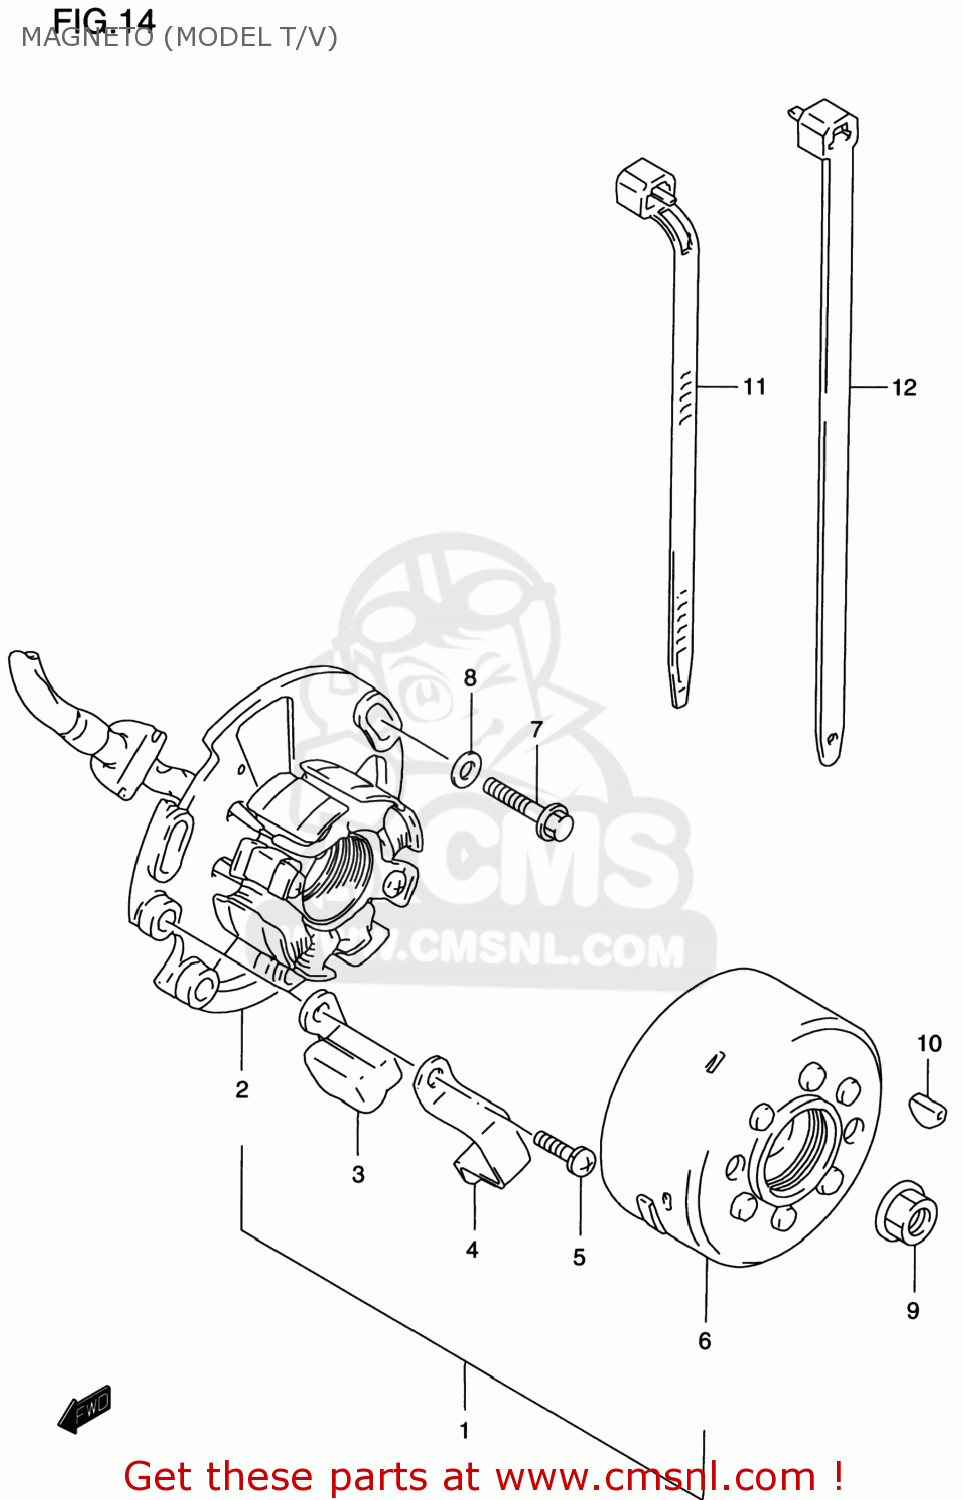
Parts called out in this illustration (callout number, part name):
1	MAGNETO ASSEMBLY
2	STARTER ASSY
3	COIL,PULSER
4	HOLDER,PICK UP COIL
5	SCREW
6	ROTOR ASSY
7	SCREW
8	WASHER
9	NUT
10	KEY
11	CLAMP L:165
12	CLAMP(L:235)
